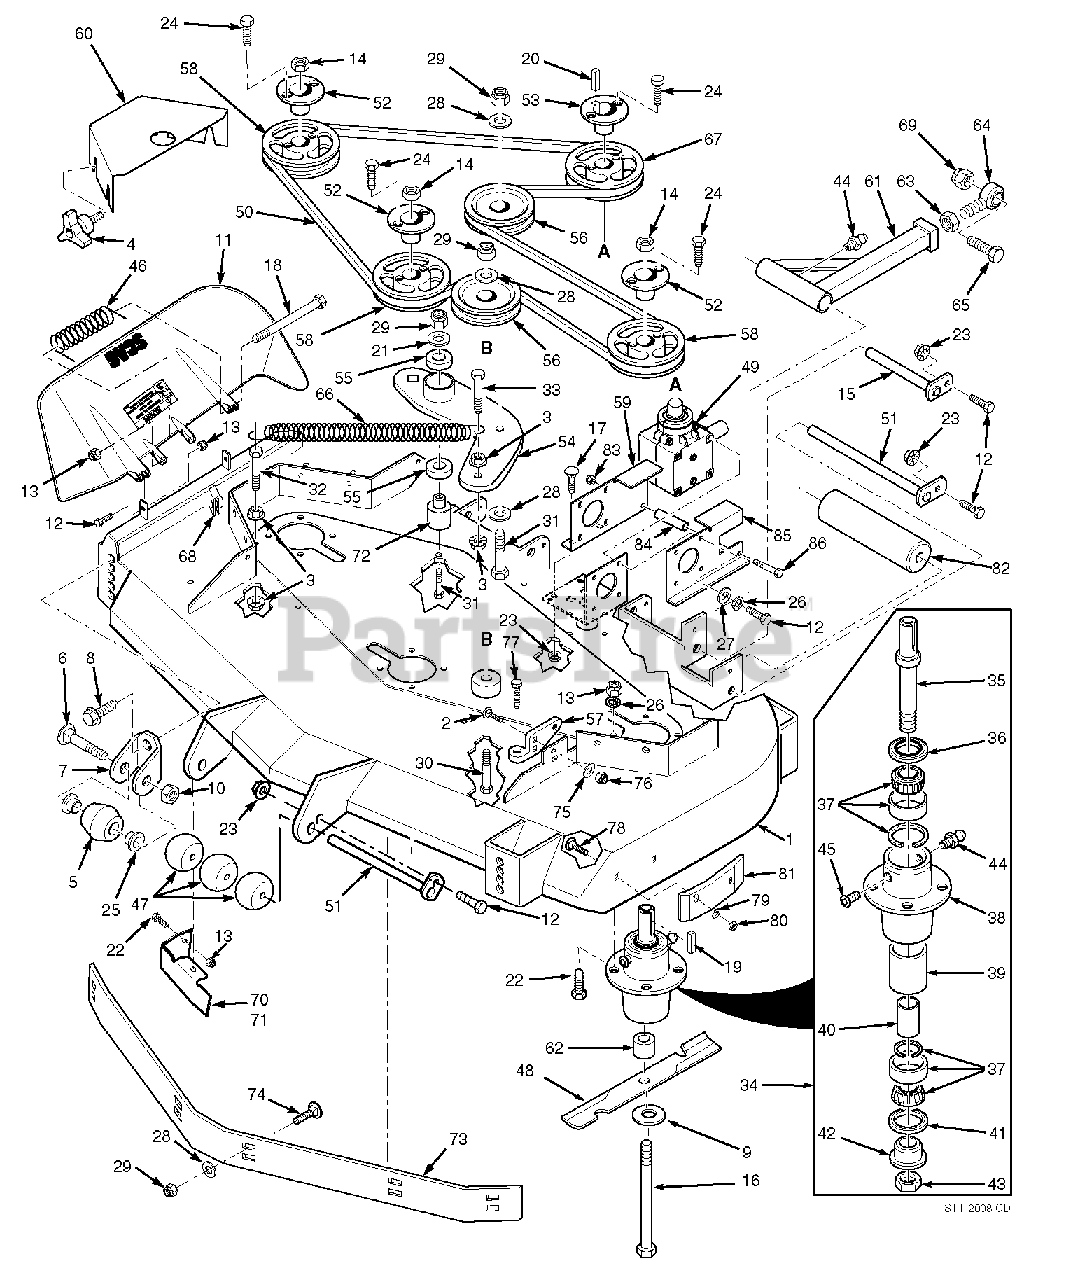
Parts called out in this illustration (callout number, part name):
1	Cutter Deck Velocity Plus
2	Bolt, Carriage 7/16-14 x 1-1/4"
3	Nut, Hex Serr. Flng 3/8-16
4	Wing nut, 3/8-16
5	Anti-Scalp Wheel
6	Bolt, Carriage 3/8-16 x 4"
7	Anti-Scalp Wheel Bracket
8	Bolt, Hex Serr. Flng 3/8-16 x 1"
9	Flatwasher, 5/8" Hardened
10	Locknut, 3/8-16 Center Lock
11	Discharge Chute
12	Bolt, Hex Head 5/16-18 x 1-3/4" - Front
13	Nut, Hex Elastic Stop 5/16-18 Grd 8
14	Nut, 5/8-11 UNC
15	Push Arm Shaft
16	Bolt, HH 5/8-11 x 9-1/2"
17	Bolt, Carriage 5/16-18 x 3/4"
18	Bolt, HH 5/16-18 x 4-1/2"
19	Key, 1/4 x 1/4 x 2"
20	Key, 1/4 x 1/4 x 1-1/4"
21	Flatwasher,3/8" (.39 x .938 x .105") HD
22	Bolt, HH 5/16-18 x 1-3/4"
23	Nut, Hex Serr. Flng 5/16-18
24	Bolt, HH 1/4-20 x 1" Grd 8
25	Bushing, .376" I.D. Oilite
26	Lockwasher, 5/16"
27	Flatwasher, 5/16" (.375 x .875 x .083")
28	Flatwasher, 3/8" (.391 x .938 x .105")
29	Nut, Hex Elastic Stop 3/8-16
30	Bolt, HH 3/8-16 x 3-1/4"
31	Bolt, HH 3/8-16 x 3"
32	Bolt, HH 3/8-16 x 1-1/2"
33	Bolt, HH 3/8-16 x 1-1/2" Grd 8
34	Spindle Assembly
35	Spindle Shaft
36	Seal, Top
37	Bearing Assembly
38	Spindle Housing
39	Spacer, Outside
40	Spacer, Inside
41	Seal, Bottom
42	Spindle Bushing, Bottom
43	Nut, Special 1-1/16-18
44	Grease Fitting
45	Relief Fitting, Tapered Spindle
46	Spring, Discharge Chute
47	Wheel, Anti-Scalp
48	Cutter Blade, 18"
49	Gearbox Assm, Deck Drive
50	Belt, Cutter Deck Drive
51	Roller Shaft
52	Tapered Hub, 1-1/8" Bore
53	Tapered Hub, 1" Bore
54	Idler Arm, Cutter Deck
55	Bearings, Ball
56	Pulley, Idler
57	Lever Assembly, Deck Level
58	Pulley, 5.75" O.D.
59	Mounting Plate, RH Gearbox
60	Belt, Cover
61	Pusharm
62	Spacer, Spindle Bottom
63	Nut, Hex Head 5/8-18 UNF
64	Rod End, 5/8" Male RH Thrd
65	Bolt, Hex Head 5/8-11 x 4-1/2"
66	Spring, Cutter Deck
67	Pulley, 6.95" O.D.
68	U-Nut, 3/8-16
69	Nut, Hex Elastic Stop 5/8-11
70	Discharge Baffle 52V
72	Pivot, Idler - Short
73	Baffle, Custom Cut 52V
74	Bolt, Carriage 3/8-16 x 1"
75	Flatwasher, 7/16" (.500 x 1.25 x .083")
76	Nut, Elastic Stop 7/16-14
77	Bolt, Deck Adjust
78	Bolt, Carraige 5/16-18 x 3/4"
79	Flatwasher, 5/16"
80	Nut, Center Lock 5/16-18
81	Wear Pad
82	Wheel, Anti-Scalp
83	Nut, Elastic Stop 5/16-18
84	Spacer, Gearbox Mount
85	Mounting Plate, LH Gearbox
86	Bolt, HH 5/16-18 x 4-3/4"
